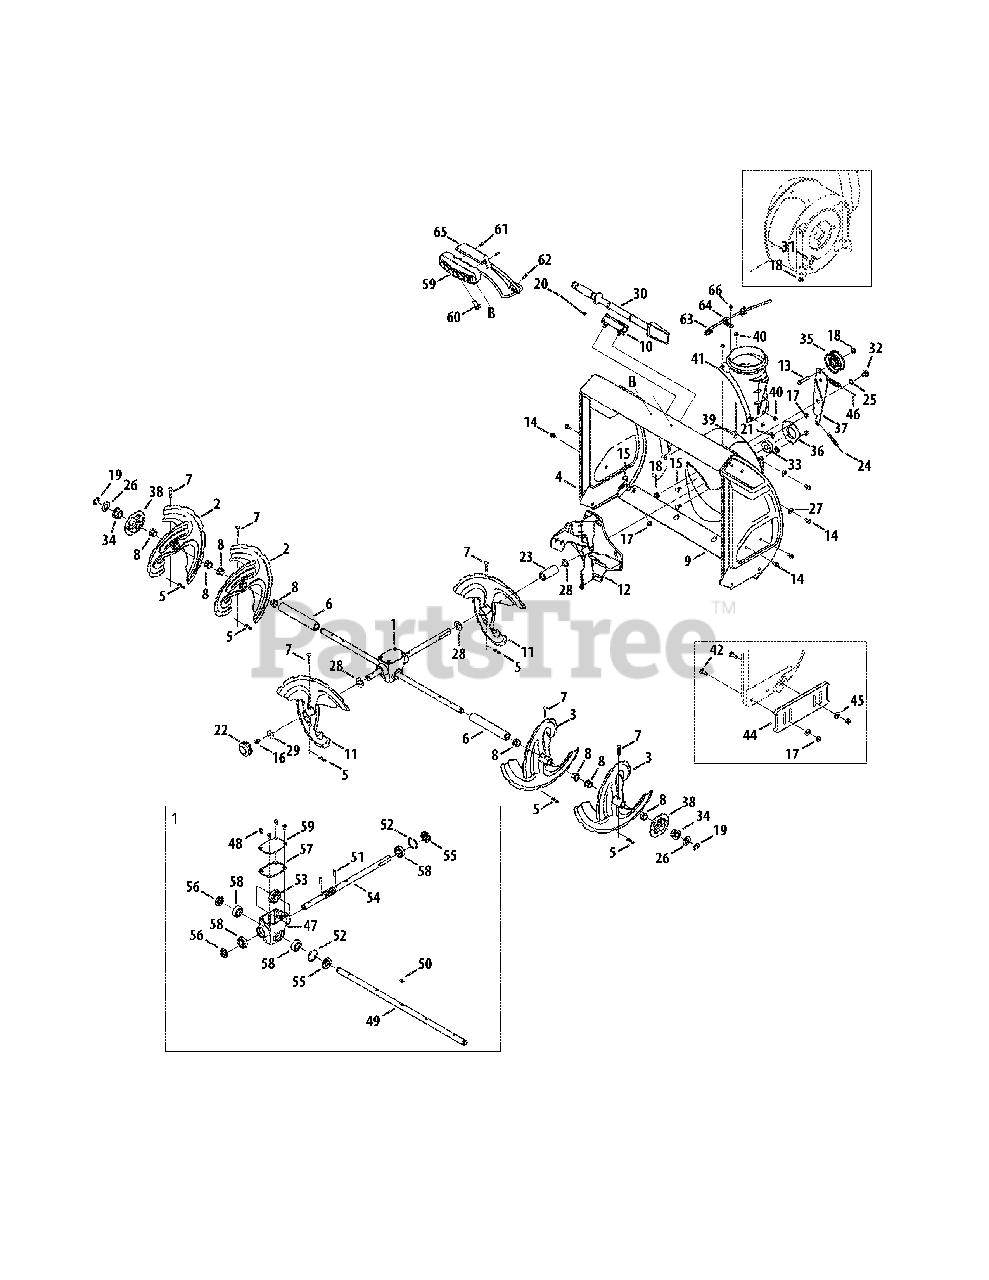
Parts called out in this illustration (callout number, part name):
1	Gearbox Assembly, Auger, 30"
2	Spiral Assembly - RH
3	Spiral Assembly - LH
4	Auger Housing, 30" w/ LED
5	Bow Tie Cotter Pin
6	Spacer, 1.25 OD x .75 ID x 7.38
8	Flange Bushing, .800 x .910
9	Shave Plate, 30"
10	Clean-out Tool Mtg. Bracket
11	Accelerator Assembly
12	Impeller Assembly
13	Hex Bolt, 3/8-16 x 1.75
14	Screw, 5/16-18 x .750
15	Carriage Bolt, 5/16-18 x .750
16	Hex Washer Screw, 5/16-18 x .500
17	Flange Lock Nut, 5/16-18
18	Flange Lock Nut, 3/8-16
19	E-ring, .75
20	Cable Tie
21	Push-On Nut, .25 Dia.
23	Spacer, 1.35 OD x .76 ID x 2.705
24	Extension Spring, .38 OD x 4.59
25	Wave Washer, .625 x .885 x .0175
26	Flat Washer, .76 x 1.49 x .06
27	Bell Washer, .340 x .872 x .060
28	Flat Washer, .793 x 1.24 x .06
29	Flat Washer, .406 x 1.92 x .060
30	Clean-Out Tool
31	Shoulder Screw, 3/8-16 x .496 x .336
32	Shoulder Screw, 3/8-16 x .625 x .17
33	Flange Ball Bearing, .75 x 1.85
34	Hex Flange Bearing, .75 ID
35	Flat Idler Pulley
36	Bearing Housing
37	Auger Idler Bracket
38	Bearing Housing
39	Carriage Screw, 1/4-20 x 0.75
39	Carriage Screw, 1/4-20 x 1.00
40	Flange Lock Nut, 1/4-20
41	Chute Adapter
42	Spacer, Carriage, 5/16-18 x 1.00
43	Gearbox Cover
44	Deluxe Slide Shoe
45	Washer, Flat, .349 x .879 x .063
46	Auger Clutch Cable
47	Auger Housing
48	Screw, 1/4-20 x 0.75
49	Axle, Auger, 30"
50	Hi-Pro Key
51	Pin, Roll, .25 x 1.0
52	Retainer Ring
53	Worm Gear, 20T
55	Seal, .75 x 40mm x .25
56	Seal, .75 x 1.375 x .25
57	Gearbox Gasket
58	Ball Bearing, .75 x 40 x 12
59	LED Headlight Assembly
60	Screw, HL, 1/4-15 x 0.50
61	Screw, 8/16 x .5
62	Screw, M6-1 x .625
63	Headlight Harness
64	Wire Clamp
65	LED Light Cover
66	Screw, TT, 1/4-20 x .500
